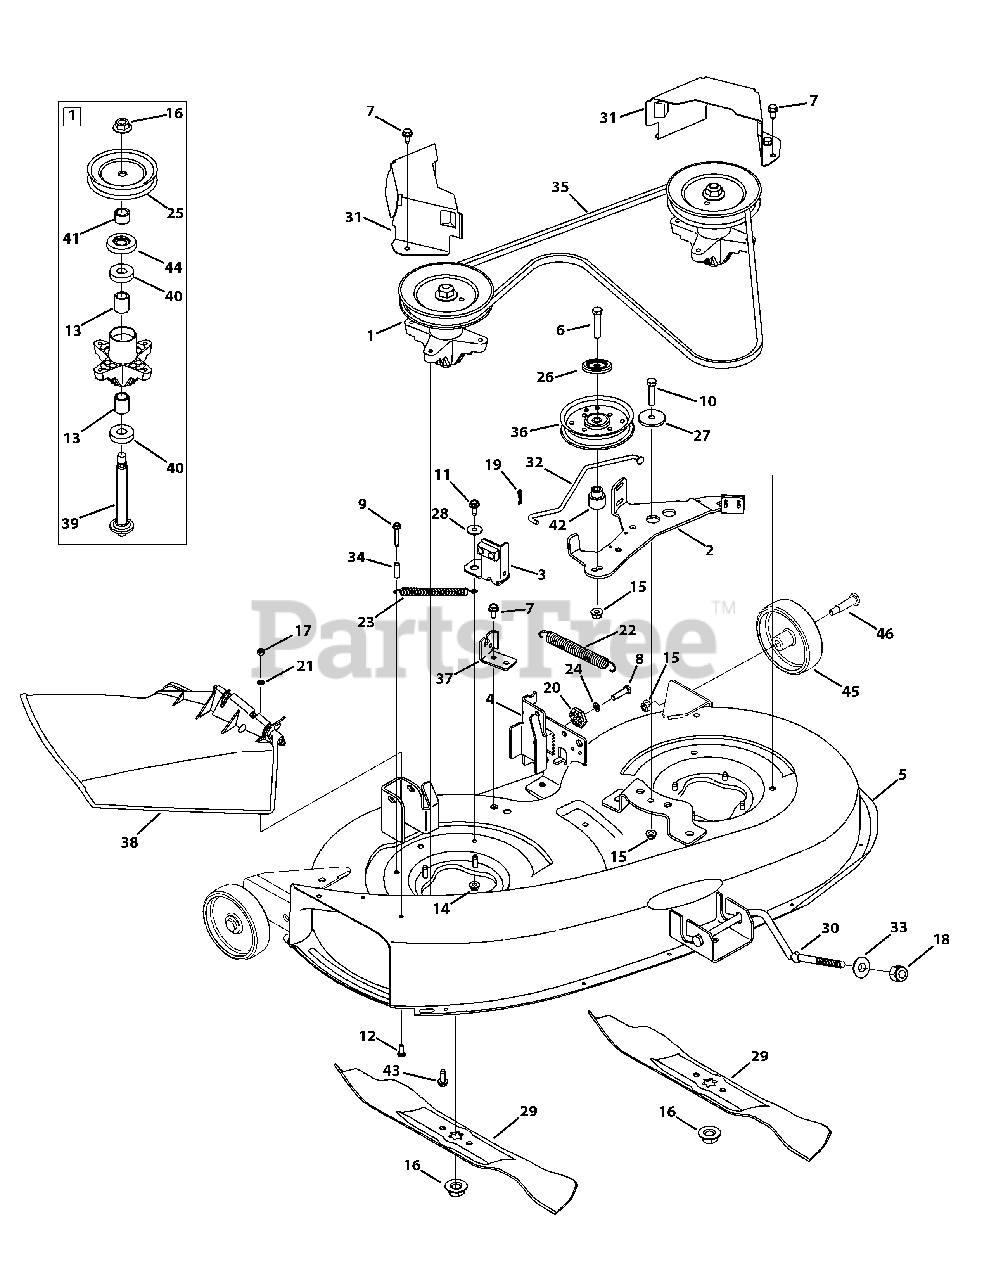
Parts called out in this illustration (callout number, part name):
1	5.75" Pulley Spindle Assembly
2	Deck Brake Assembly
3	Deck Brake Assembly
4	LH Deck Hanger Bracket
5	38" Deck
6	Hex Screw, 3/8-16 x 1.75
7	Screw, 5/16-18 x .750
8	Hex Screw, 5/16-18 x 1.25
9	Screw, 1/4-20 x 1.50
10	Hex Screw, 3/8-16 x 1.25
11	Hex Screw, 5/16-18 x .75
12	Hex Screw, 1/4-20 x .62
13	Spacer, .80 x 1.10 x 1.322 LG
14	Flangelock Nut, 5/16-18
15	Flangelock Nut, 3/8-16
16	Flange Nut, 5/8-18
17	Flangelock Nut, 1/4-20
18	Hex Nut, 1/2-13
19	Bow-tie Cotter Pin
20	Deck Adjuster Gear
21	Push Nut, .25 x .50
22	Extension Spring, .75 x 6.375
23	Extension Spring, .500 x 6.375
24	Lock Washer, 5/16
25	Deck Pulley, 5.75
26	Pulley Cap
27	Shoulder Spacer, .8840 x .190
28	Shoulder Spacer, .5000 x .1475
29	3 in 1 Blade
30	38" Front Adjust Deck Rod
31	Belt Cover
32	38" Brake Control Rod
33	Deck Lift, Pivot Cup
34	Spacer, .260 x .375 x 1.030
35	V Type Belt
36	Idler Pulley
37	Deck Engage Cable Bracket
38	Chute Assembly
39	Spindle Shaft, 5.50
40	Ball Bearing, .787ID x 1.85 OD x .551
41	Spacer, .820 x 1.150 x .480 LG
42	Shoulder Spacer, Idler
43	Screw, 5/16-18 x 0.750
44	Bearing Shield
45	Deck Wheel, 5.0 x 1.38
46	Shoulder Bolt, .496 x 1.525, 3/8-16
